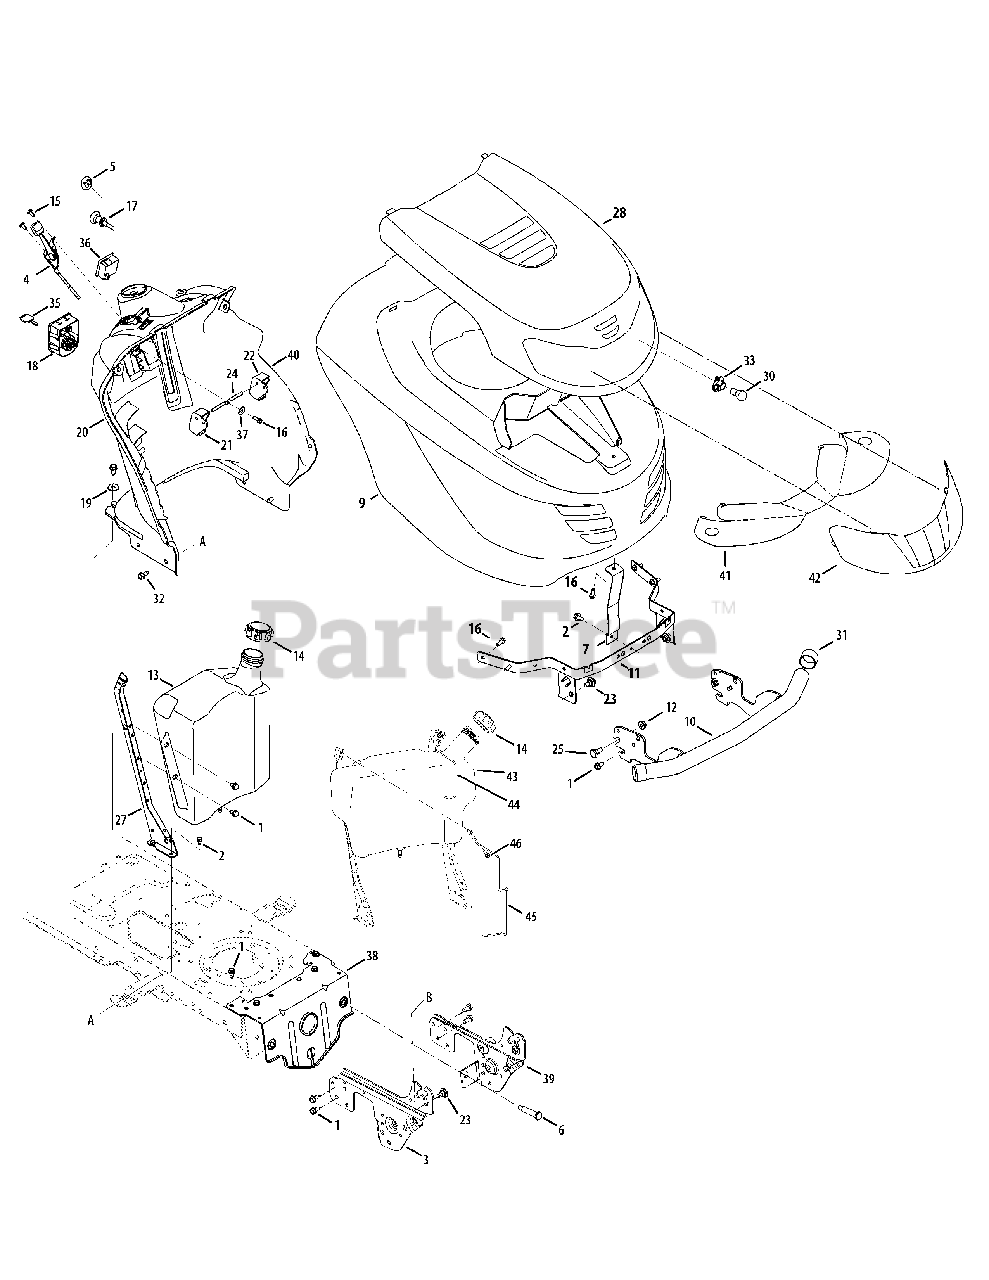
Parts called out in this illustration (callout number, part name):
1	S-Tapp Scr 5/16-18 x .75
2	Hex Wash S-Tapp Scr 1/4-20 x .50
3	RH Pivot Support Bracket
3	RH Pivot Support Bracket (50 & 54" decks)
4	Throttle/Choke Cont. Cable 25" Lg. (Sin gle)
4	Throttle/Choke Cont. Cable 46.5" Lg. (Twin)
4	Throttle Control Cable 46.5" Lg. (Twin w/sep choke)
6	Shoulder Bolt .5 x 2.38, 3/8-16
7	Hood Support Bracket
9	Grill Style "G" (w/side fill)
11	Hood Pivot Bracket
12	Hex Lock-Nut 3/8-16 Gr.B
13	Fuel Tank 3 Gal.
14	Cap-Fuel
15	Torx Mach. AB-Tapp Scr. 1/4-14 x .625 Lg
16	Hex Tapp Scr 1/4 x .75" Lg.
17	Choke Cable 37.5" Lg.
18	Ignition Switch
20	Dash Panel (Elect. PTO w/ fuel level win dow)
21	Cruise Control Button
22	Parking Brake Button
23	Shoulder Screw .43 x .29, 5/16-18
25	Shoulder Scr. .498 x .340: 3/8-16
27	RH Dash Support Plate
28	Upper "G" Style Hood
30	Miniature Lamp 12V Socket Type
32	Screw 5/16-12 x .75
33	Socket
35	Ignition Key w/Plastic Cover
35	Ignition Key w/o Plastic Cover
36	Wire Harness (w/Hour Metre)
37	Flat Washer .281 x .50 x .063
38	Pivot Bar Bracket
39	LH Pivot Support Bracket
39	RH Pivot Support Bracket (50 & 54" decks)
40	Dash Panel (Elect. PTO w/ fuel level window)
41	Reflective Label
42	Lens (Style G)
43	Fuel Tank 2.75 Gal.
44	Tank Support Rod LH
45	Tank Support Rod RH
46	Hex TT Screw 1/4-20 x .75
